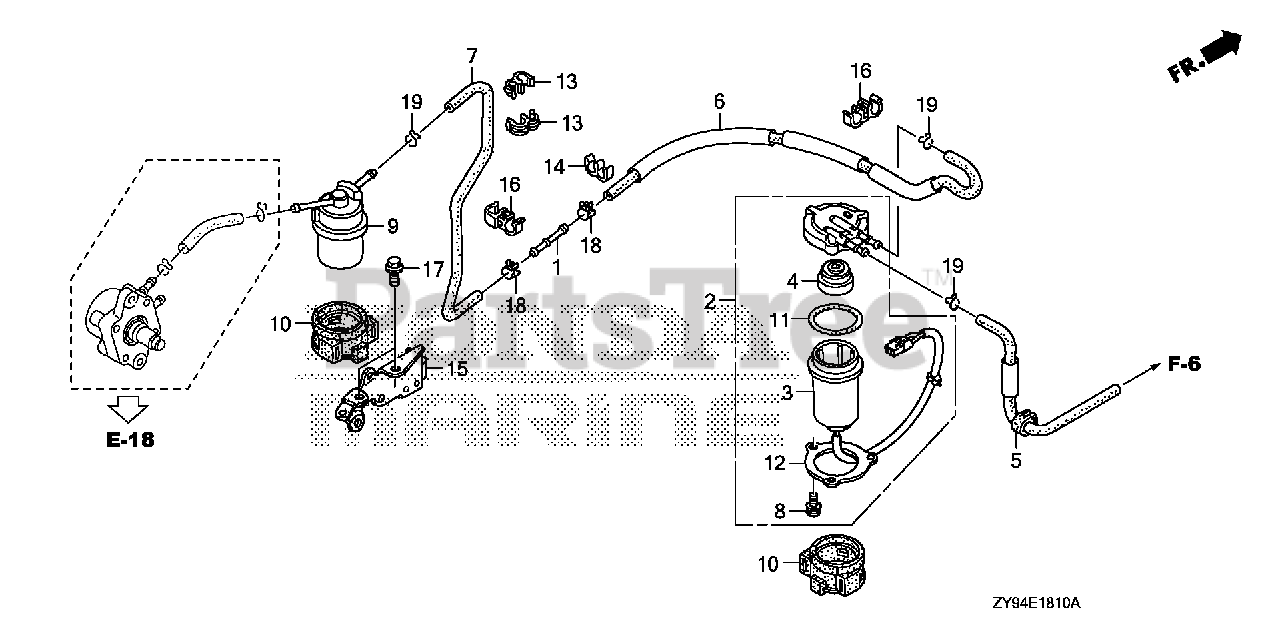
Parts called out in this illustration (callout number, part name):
1	JOINT, FUEL FEED HOSE
2	SEPARATOR ASSY., WATER
3	CUP, WATER SEPARATOR
4	BUFFER, PLATE
5	TUBE A, FUEL
5	TUBE A, FUEL (TO 1016251)
6	TUBE B, FUEL
7	TUBE C, FUEL
8	SCREW, PAN (5X12)
9	FILTER, FUEL
10	SUSPENSION, STRAINER
13	CLAMP, TUBE (7.5-11.5) (BLACK)
14	CLAMP, TUBE
15	BRACKET B, HARNESS CLIP
16	CLIP, SENSOR HOSE
17	BOLT, FLANGE (6X14) (CT200)
18	CLAMP, TUBE (D12)
19	CLIP, TUBE (B12)
